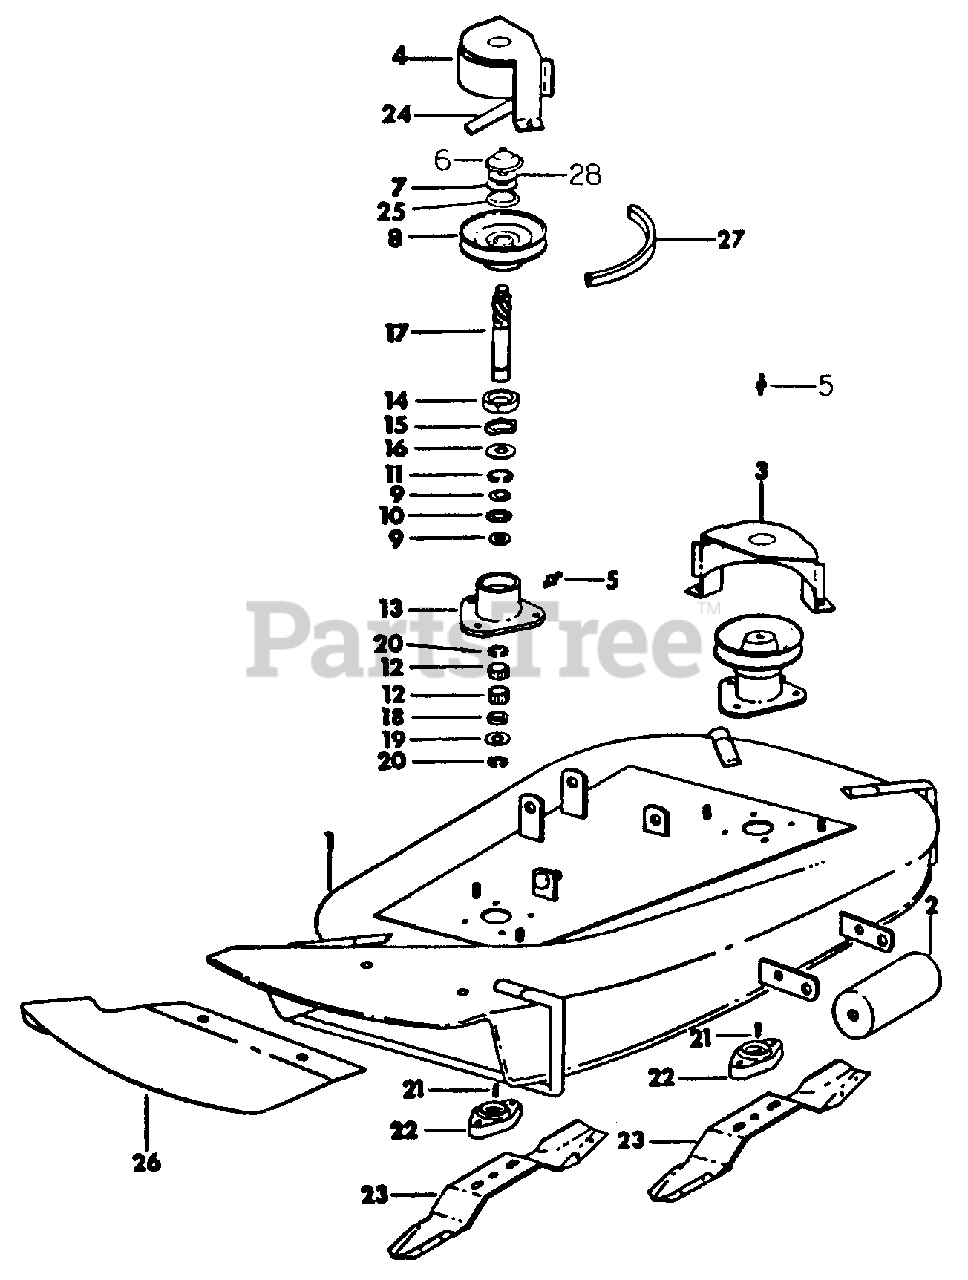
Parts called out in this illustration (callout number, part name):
1	Housing Assy, Mower - See Service Bulletin CC-091
2	Roller, Front
5	Fitting, 3/16 Str Drive Lub
6	Cut, Seal
7	Washer, Special
8	Pulley, Outer
9	Race, Needle Thrust Bearing
10	Bearing, Needle
11	Ring, 1-1/4 Internal Retaining
12	Bearing, Needle
13	Housing, Blade Shaft
14	Brake, Insert
15	Washer, Wave
16	Washer, Stop
17	Shaft, Blade
18	Seal, Oil
19	Washer, Thrust
20	Ring, 3/4 External Retaining
21	Key, 3/16 X 1/2 Sq Parallel
22	Adapter, Blade
23	Blade, Mower, 36 Inch
24	Not used in this application
25	Not used in this application
26	Package, 36 In. Mower Deflector
27	Belt, Mower Drive, 1/2 X 68.5 In. Effective Length
28	Washer, .906 X 1.25 X .027 Znd
